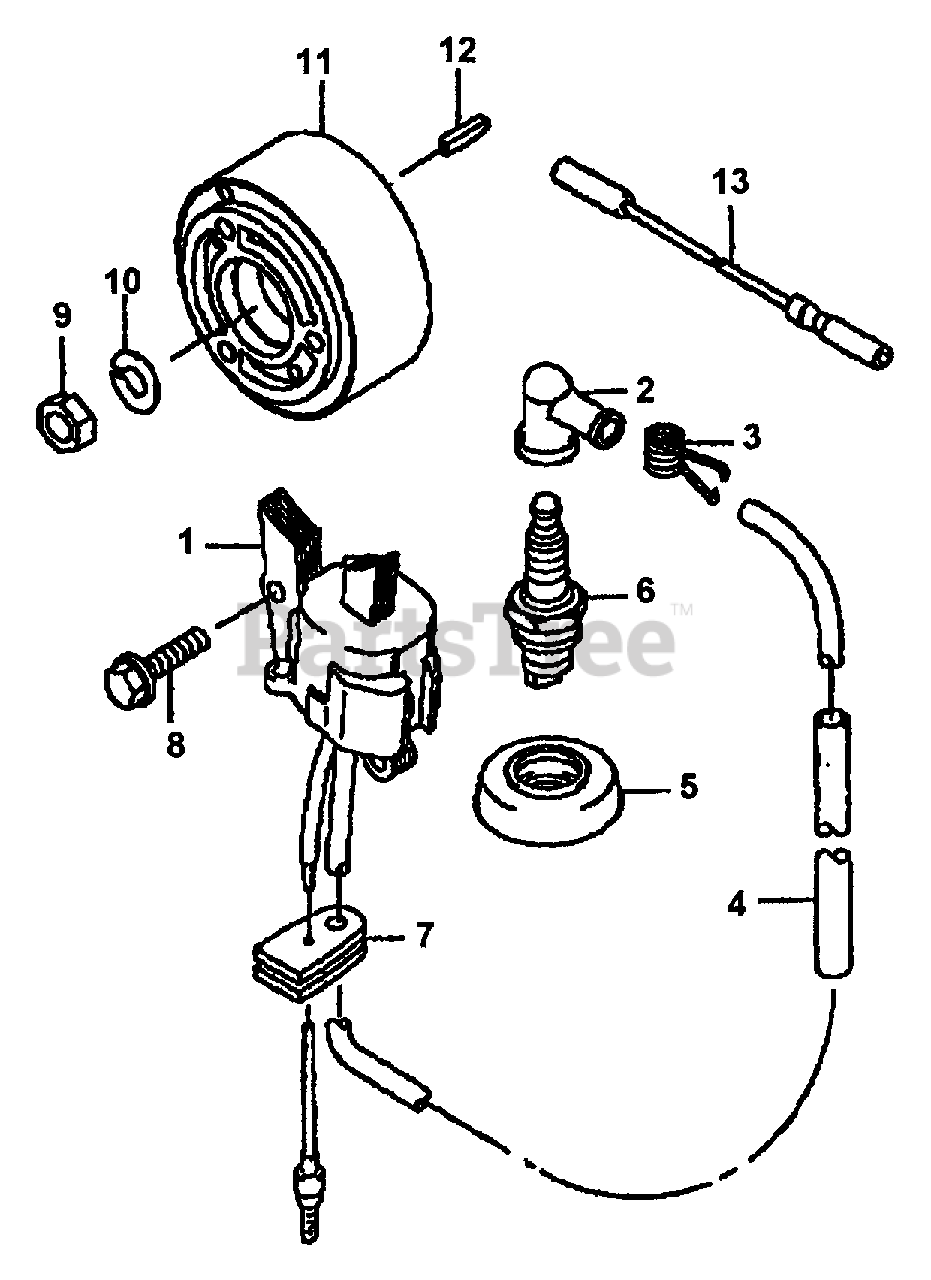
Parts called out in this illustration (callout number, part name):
1	COIL ASSY.
2	CAP, BOOT
3	TERMINAL
4	TUBE, WIRE
6	SPARK PLUG
8	BOLT
9	NUT
11	FLYWHEEL
13	LEAD WIRE
